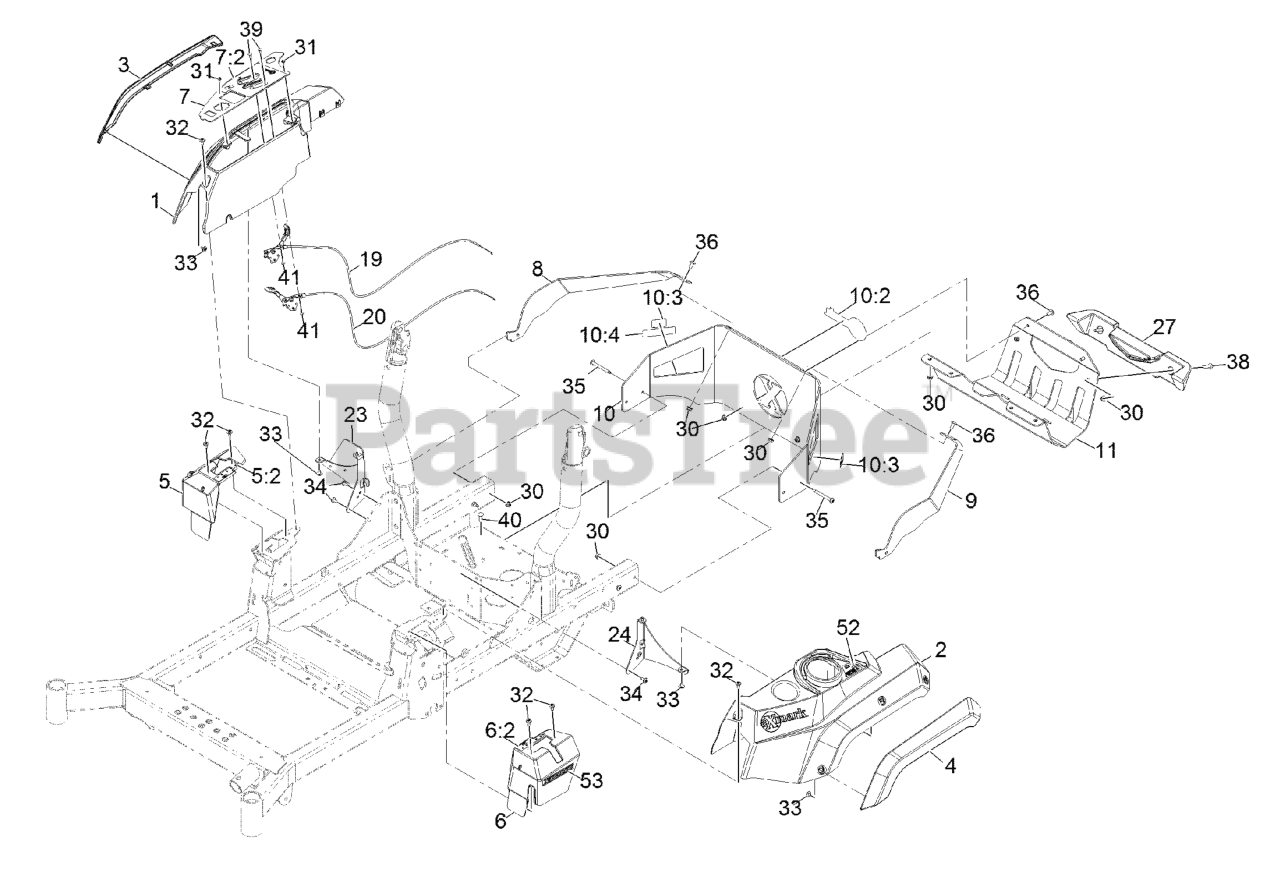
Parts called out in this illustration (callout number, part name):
1	CONSOLE-EXMARK, RH
2	CONSOLE, LH
3	FENDER-RH
4	FENDER-LH
5	COVER-CONTROL, MOTION (RH
5:2	Decal-Control, Motion (RH)
6	COVER-CONTROL, MOTION (LH
6:2	Decal-Control, Motion (LH)
7	CTRL PANEL ASM W/DECAL
7:2	DECAL-CONTROL PANEL
8	SUPPORT-UPPER, RH
9	SUPPORT-UPPER, LH
10	REAR GUARD ASM
10:2	DECAL-EXMARK LOGO
10:3	DECAL-WARNING
10:4	DECAL-ARRESTOR, SPARK
11	GUARD-MUFFLER
19	CABLE-CONTROL, CHOKE
20	CABLE-CONTROL, THROTTLE
23	SUPPORT-CONSOLE, RH
24	BRACKET-CONSOLE, LH
30	NUT-HF, NI
31	SCREW-HWH
32	SCREW-SHOULDER
33	SCREW-TORX
34	SCREW-TORX
35	SCREW-TORX
36	SCREW-TORX
38	SCREW-TORX
39	BOLT-CARR
40	SCREW-CARR
41	NUT-LOCK, NI
52	DECAL-FILL, FUEL
53	DECAL-X-SERIES
